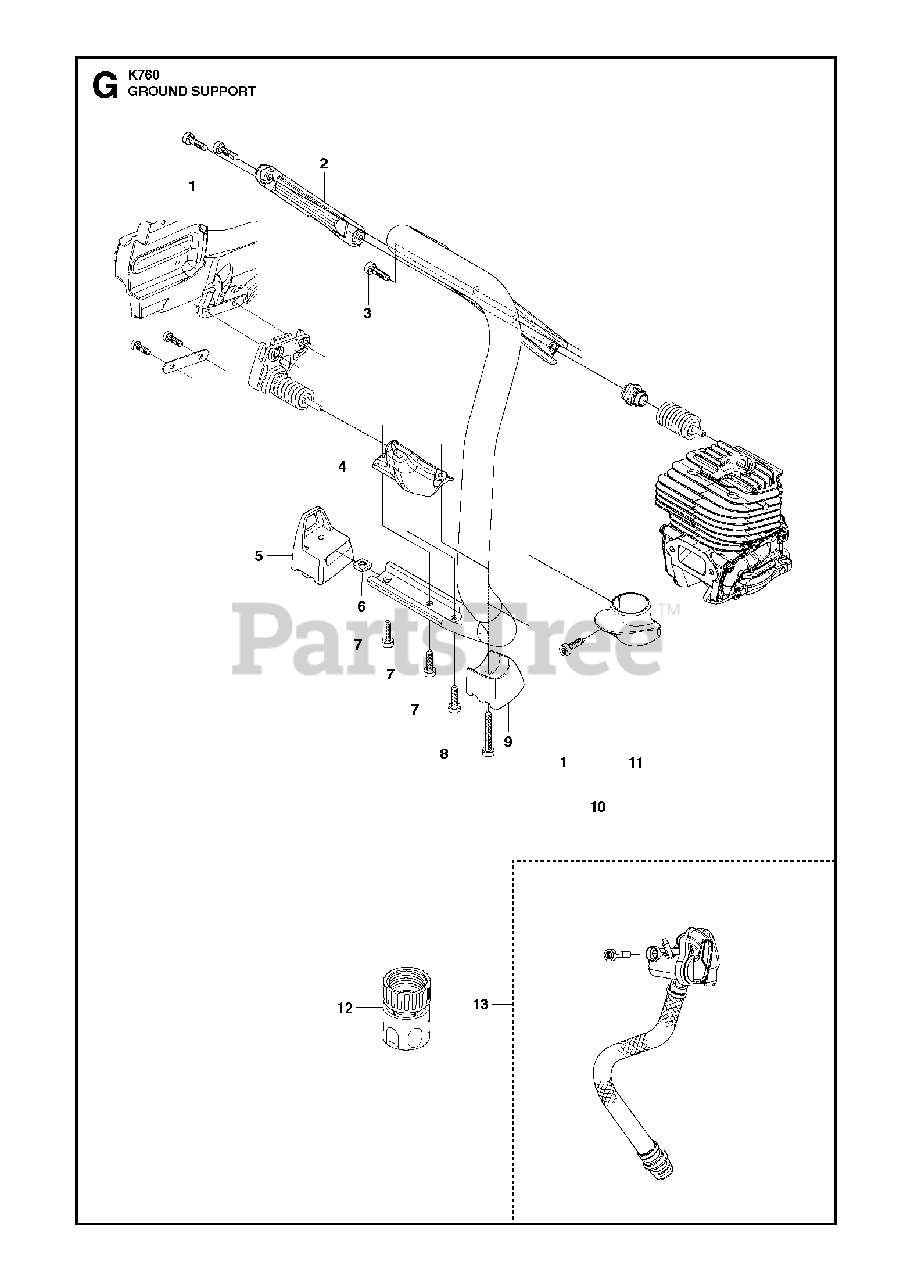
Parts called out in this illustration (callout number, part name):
1	SCREW ITXSCT
2	HOSE GUARD
3	SCREW ITXSCM
4	SPRING RETAINER
5	GROUND SUPPORT
7	SCREW ITXSCM
8	SCREW ITXSCM
9	GROUND SUPPORT
10	HANDLE ASSYIncl. 1,11
12	COUPLERUSA, Canada
13	HOSE KIT
